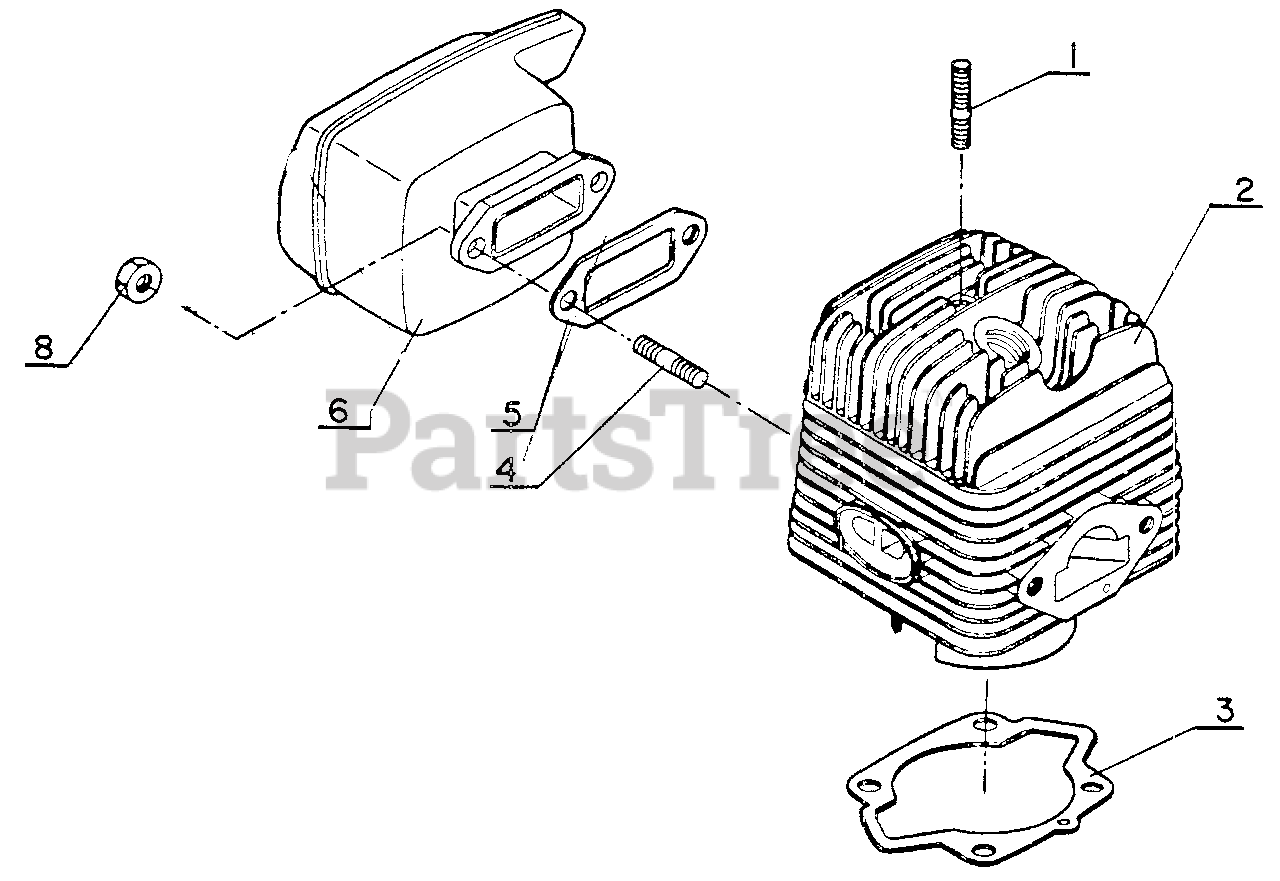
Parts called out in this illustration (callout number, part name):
2	CYLINDER
3	GASKET, CYLINDER
4	BOLT, STUD
5	GASKET, EXHAUST
8	NUT, LOCK
